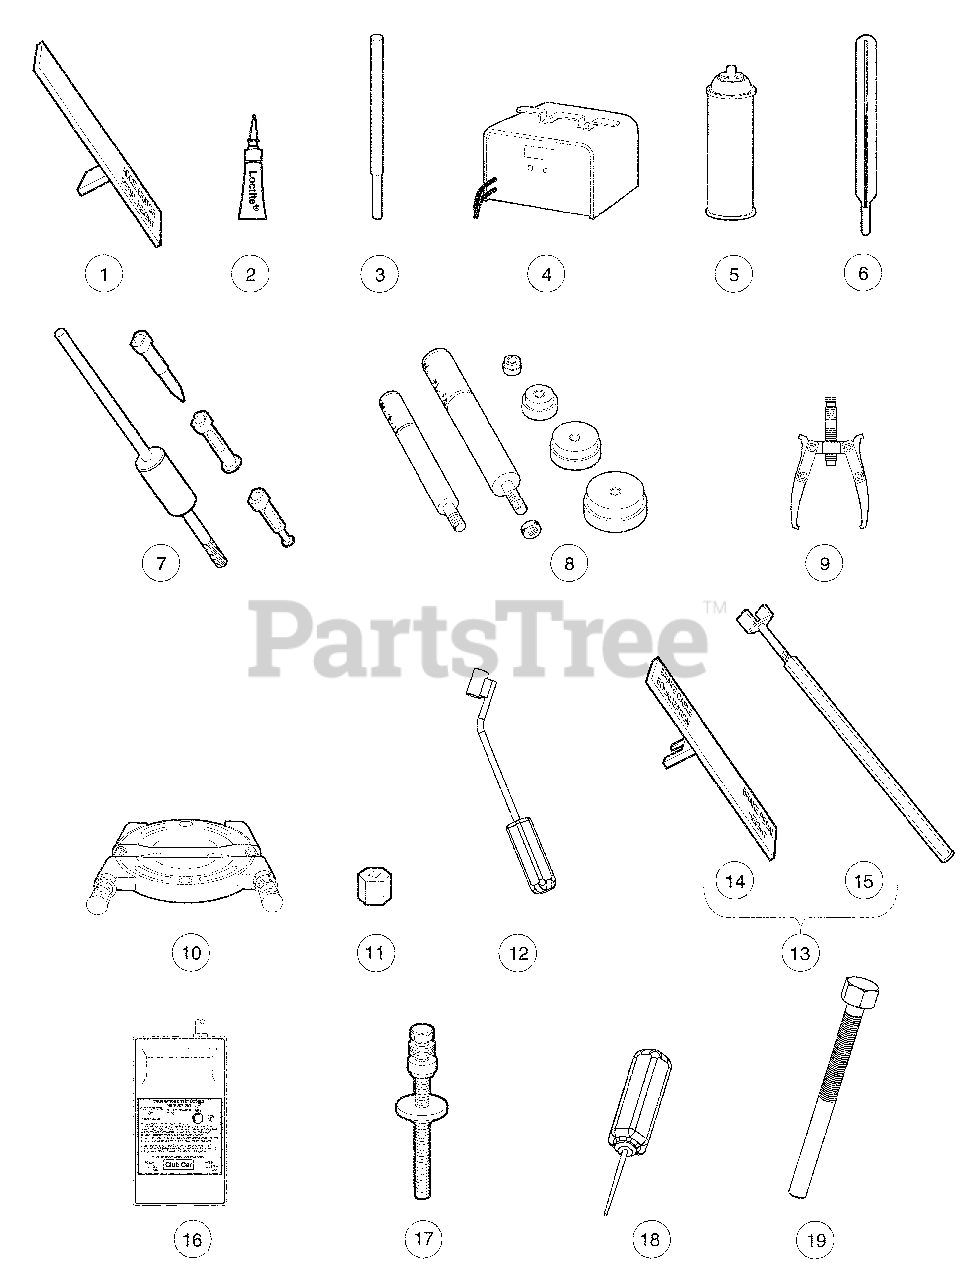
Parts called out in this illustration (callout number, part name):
1	Accelerator Pedal Adjustment Tool
2	Adhesive, Guide Ring, 3-Gram Tube
4	Battery Discharge Machine, 36/48 Volt
5	Battery Terminal Protector Spray
6	Battery Thermometer
7	Bearing and Oil Seal Remover Assembly
8	Bearing Driver Set
9	Bearing Puller
10	Bearing Puller Wedge Attachment
11	Brake Adjustment Tool
12	Brake Cable Release Tool
13	Brake Pedal Adjustment Tool Kit
14	Brake Pedal Adjustment Tool
15	Brake Pedal Tension Tool
16	Calibration Test Module
17	Cam Installation Tool
18	Charger Bezel Tool
19	Clutch Removal Tool (for 4x4 vehicles)
20	Clutch Tool Kit
21	Clutch Alignment Tool
22	Drive Clutch Puller
23	Drive Clutch Hub Puller
24	Driven Clutch Cam Puller
25	Driven Clutch Puller Plug
26	Drive Clutch Holder Tool Assembly
27	Press Weldment
28	Drive ClutchFixed Sheave Tool (for 4x4 vehicles)
29	Driven Clutch Spring Compression Base
30	Driven Clutch Spring Compression Collar
31	Driven Clutch Spring Compression Nut
32	Drive Clutch Spider Removal Tool
33	Communication Display Module
34	Compression Gauge and Adapter
35	Continuity Tester
36	Cutter, Valve Seat, #122
37	Cutter, Valve Seat #115
38	Wrench, T, #505
39	Adapter, T-Wrench
40	Cutter, Valve Seat, 60 Degree (requires item 51)
41	Pilot, 6.6 MM
42	Pilot, 6.62 MM
43	Pilot, 6.65 MM
44	Dry Moly Lubricant
45	Flywheel Puller Kit
46	Gauge, Carburetor Float Level
48	Governor Shaft Installation Tool
49	Hydraulic Brake Adjuster (for HUV 4213)
50	Hydrometer
51	Internal Retaining Ring Pliers
52	IQ Display Module (IQDM) Kit
53	IQ Display Module (IQDM-P) Kit
54	Adaptor, Cable
55	IQDM Series 2 Cable
56	IQDM Series 1 Cable
57	Liquid Gasket
58	Moly-Teflon Lubricant (4-oz. (113-gram) tube)
59	Paint, Touch-Up – Beige
59	Paint, Touch-Up – Black
59	Paint, Touch-Up – Burgundy
59	Paint, Touch-Up – Classic Blue
59	Paint, Touch-Up – Dark Gray
59	Paint, Touch-Up – Dark Green
59	Paint, Touch-Up – Gray
59	Paint, Touch-Up – Red
59	Paint, Touch-Up – Royal Blue
59	Paint, Touch-Up – White
60	Paint, Precedent Underbody – Gray
61	Paint Pen, Touch-Up, Precedent Underbody – Black
62	Piston Ring Compressor Kit (FE290, FE350 and FE400 engines)
63	Piston Ring Pliers
64	Puller, Special Use (for Kubota D722 Diesel Engines)
65	Retaining Ring Pliers, 45° External
66	Retaining Ring Pliers, 90° Internal
67	Safety First Card (50 per pack)
68	Seal Puller
69	Spanner Wrench
70	Steering Column Bearing Press Tool
71	Steering Column Retaining Ring Tool
72	Steering Wheel Puller Tool
73	Tachometer
74	Tachometer Diesel Probe (for use with item 73)
75	Transaxle Axle Seal Tool
76	Transaxle Pinion Seal Tool
77	Transmission Tool Kit
82	Valve Clearance Adjuster Screw Holder (for FE290 engines only)
83	Valve Guide Driver
84	Valve Guide Reamer (FE290, FE350, and FE400 only)
85	Valve Guide Reamer, 6.6 mm
86	Valve Seat Cutter Guide
87	Valve Seat Cutter T-Wrench
88	Valve Seat Cutter, 45° (32 mm diameter) (for FE290 engines only)
89	Valve Seat Cutter, 45°/30° (35 mm diameter)
90	Valve Spring Compressor
91	Volt Ohm Meter
92	Tool, Tensioning, Starter Generator
